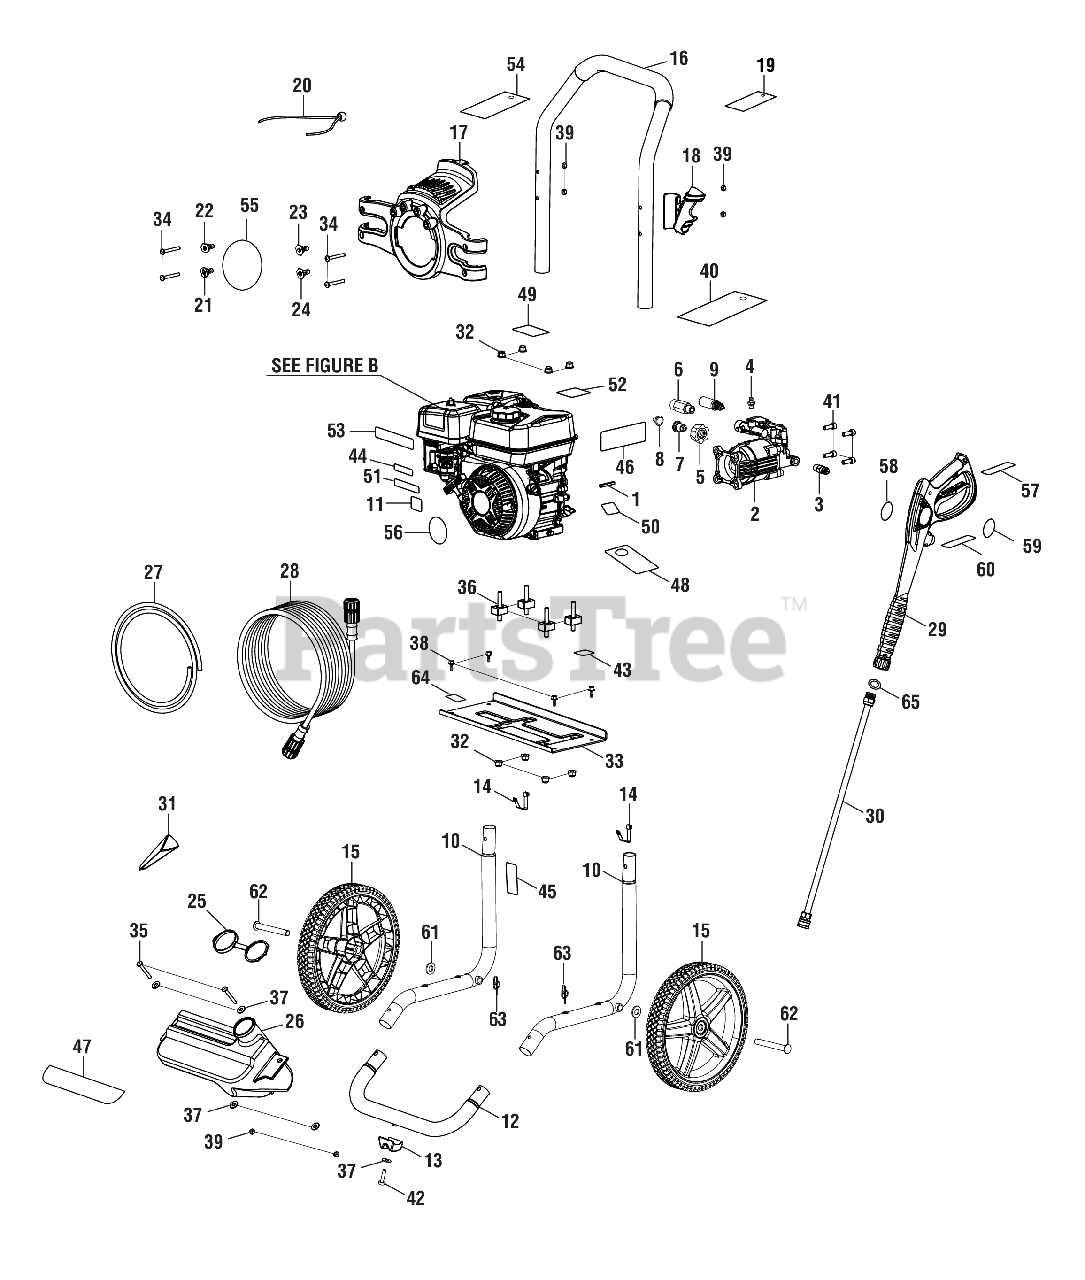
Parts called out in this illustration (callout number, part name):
1	Output Shaft Key (3/16 in. x 40 mm)
2	Pump
3	Thermal Release Valve.
4	Detergent Injector Assembly
5	Inlet Filter Adapter/Brass Insert
6	Outlet Tube
7	Inlet Filter Connector
8	Filter Screen (Pump Inlet)
9	Unloader Valve Assembly
10	Main Frame Assembly
11	Choke/Fuel Valve Label
12	Front Frame Assembly
13	Rubber Foot
14	Lock Button w/Spring Clip.
15	Wheel (12 in.)
16	Handle Assembly
17	Hose and Nozzle Holder Assembly
18	Trigger Handle Holder
19	Quick Start Hangtag
20	Bungee Cord and Bead Assembly
21	0deg Nozzle
22	25deg Nozzle
23	40deg Nozzle
24	Soap Nozzle (Blue)
25	Soap Tank Cap
26	Soap Tank
27	Chemical Siphon Tube
28	High Pressure Hose (25 ft.)
29	Trigger Handle Assembly
30	Extension Wand
32	Lock Nut (M8 x 1.25 mm, Flange)
33	Engine Plate
34	Bolt (M6 x 48 mm, Button Hd.)
35	Screw (M6 x 1 x 48 mm, T30 Torx Pan Hd.)
36	Engine Isolator
37	Washer (1/4 in.)
38	Flange Bolt (M6 x 1 x 16 mm, Hex Hd.)
39	Lock Nut (M6 x 1)
40	Danger Hang Tag
41	Screw (5/16-24 x 23 mm, Hex Soc. Cap Hd.)
42	Screw (M6 x 1.25in., T30 Torx Pan Hd.)
43	Oil Fill Location Label
44	Choke Label
45	Combustion Label (English/Spanish)
46	Danger Label
47	Detergent Tank Label
48	Hangtag (Oil Dipstick)
49	No E85 Label
50	Engine Switch Label
51	Fuel Valve Label
52	Hot Surface and Exhaust Label
53	Warning Label (Inquiries)
54	Nozzle Instructions Hangtag
55	Performance Label
56	Recoil Label
57	Label (Trigger Handle Warning, French & Spanish)
58	Powerstroke Trigger Wand Logo Label
59	Label (Trigger Handle Warning, English)
60	Trigger Handle Specifications Label
61	Washer (1/2 in.)
63	Hitch Pin
64	Data Warnings Label (English/Spanish)
65	O-Ring (9.5 x 2.65, NBR Shore A 90)
